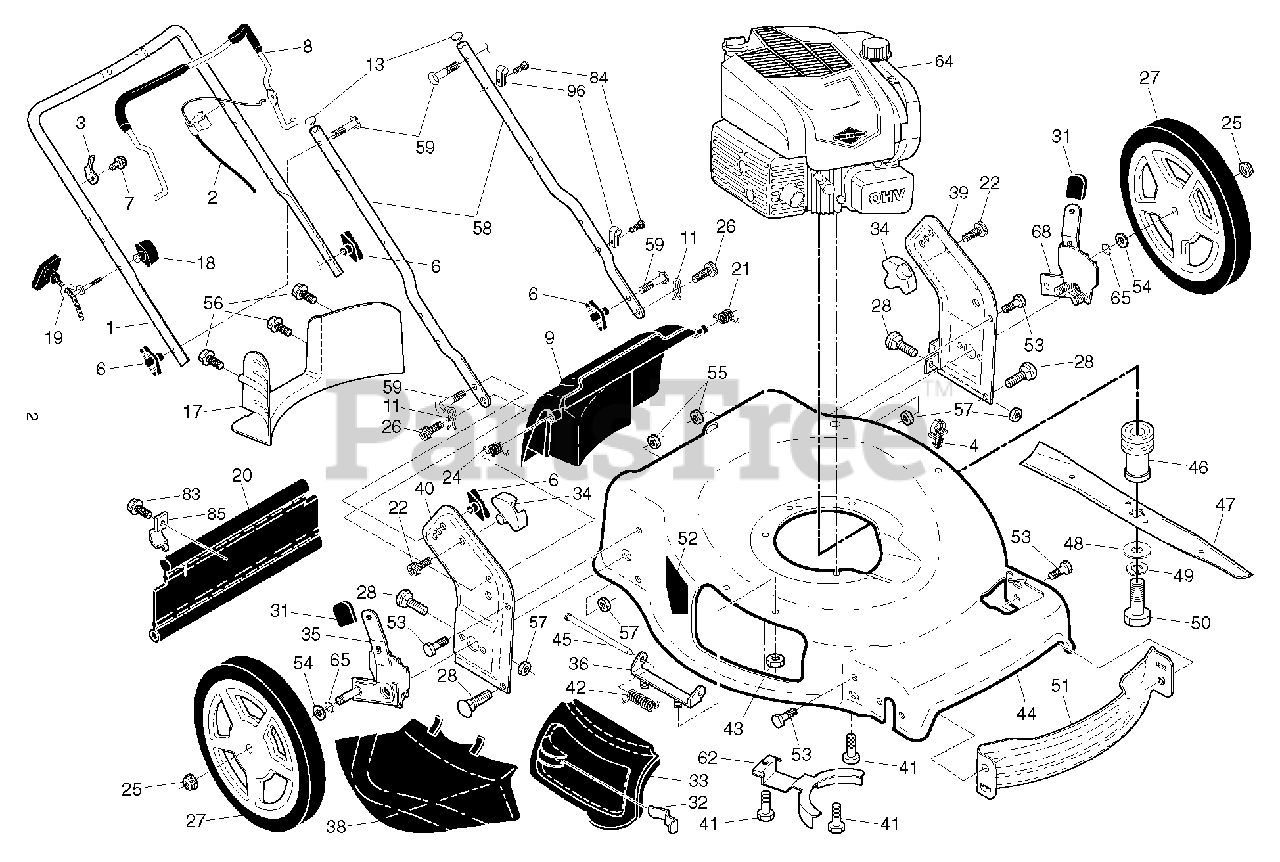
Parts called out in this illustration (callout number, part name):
1	HANDLE.UP.DST.SS/VS.FG/RG.NHB
2	CABLE.MZR.FGD.PLUS
3	BRACKET.UPSTOP.RT
4	PUSH CLIP
6	KNOB.HANDLE.PLASTIC.STAR.BLACK
8	Bail, Om Strt Mzr Marig 421
9	DOOR.REAR.22PLUS.MB.FGD.SAFETY
11	COTTER.HAIRPIN.DOOR/HANDLE.PIV
13	PLUG.PLASTIC.7/8".14-20.GAUGE
17	BAFFLE.22PLUS.FGD.REAR.
18	T-KNOB.NEW ROPE GUIDE
19	Rope Guide, Blk Zinc Chrom
20	SKIRT.REAR.22PLUS.RGD/FGD.NEW
21	SPRING.LH.GRAY
22	SCREW.PAN.HEAD.#10
24	SPRING.RH.GRAY
25	NUT.HEX.FLANGE.3/8-16.LOCKNUT
26	SCREW,DOOR/HANDLE.PIVOT
27	WHEEL.12X1.75.5SP.RAD3.MARIGOL
28	Carriage Bolt, 5/16-18 X 5/8
31	SELECTOR KNOB
32	LATCH.DOOR.ZINC
33	DOOR.MULCH.22.BLACK.MULTI-BRAN
34	BRACKET.GRASSBAG.ATTACHING.BLK
35	ADJUSTER.ASM.9POS.HW.R/R
36	BRACKET.ASM.HINGE.21.FWGD.
38	DEFLECTOR.CLIPPING.22.BLACK
39	Handle Bracket Assembly, LH 22+ Black
40	Handle Bracket Assembly, RH 22+ Black
41	BOLT 3/8-16X1-1/8
42	SPRING.TORSION
43	NUT.HEX.FLANGE.1/4
44	HOUSING.22.FWD.MC.WO.NB.BLACK
45	ROD.HINGE.21
46	ADAPTOR BLADE 25MM STAR
47	BLADE.22PLUS
48	WASHER,HARDEN
50	SCREW, HEX HD 3/8-24 X 1-3/8
51	BAFFLE.FRONT.22.PLUS
52	No Step Decal
53	BOLT.5/16HEX.WHS.HD
54	WASHER PM
55	NUT.HEX.FLANGE.1/4
56	SCREW.HX.13X.750
57	NUT.FLANGE.5/16
58	HANDLE.LOWER.22+.BT.2PC.BLK
59	BOLT, HANDLE 5/16-18X1.75
62	BRACKET.ENG/BELTKEEPER
65	O-RING..070X.487.NEOPRENE
68	ADJUSTER.ASM.9POS.HW.R/L
83	TAPPING SCREW
84	FASTENER.PUSH.O.250X0.783
85	BRACKET.SKIRT.22+.BZP
96	CLIP.CABLE.BLK
